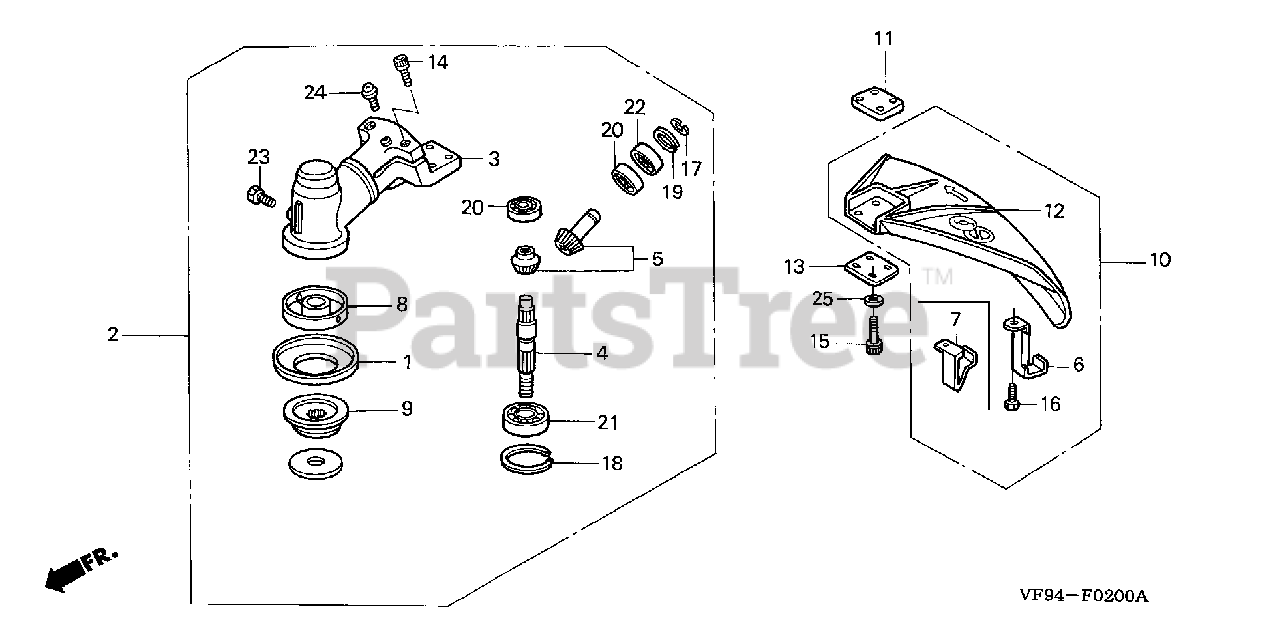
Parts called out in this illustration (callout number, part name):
1	GUARD, GRASS
2	CASE ASSY., GEAR
3	CASE, GEAR
4	SHAFT, GEAR
5	GEAR ASSY., BEVEL
7	PLATE, NYLON CUTTING
8	HOLDER A, BLADE
9	HOLDER B, BLADE
10	DEFLECTOR ASSY., GRASS
11	SPACER, DEFLECTOR
12	DEFLECTOR, GRASS
13	PLATE, DEFLECTOR
14	BOLT, SOCKET (5X20)
15	BOLT, SOCKET (5X30)
16	BOLT, SOCKET (5X15)
17	CIRCLIP (OUTER) (10MM)
18	CIRCLIP (INNER) (28MM)
19	CIRCLIP (INNER) (26MM)
20	BEARING, RADIAL BALL (6000)
21	BEARING, RADIAL BALL (6001LL)
22	BEARING, RADIAL BALL (6000Z)
23	BOLT, HEX. (6X8)
24	SCREW-WASHER (5X10)
25	WASHER, PLAIN (5MM)
